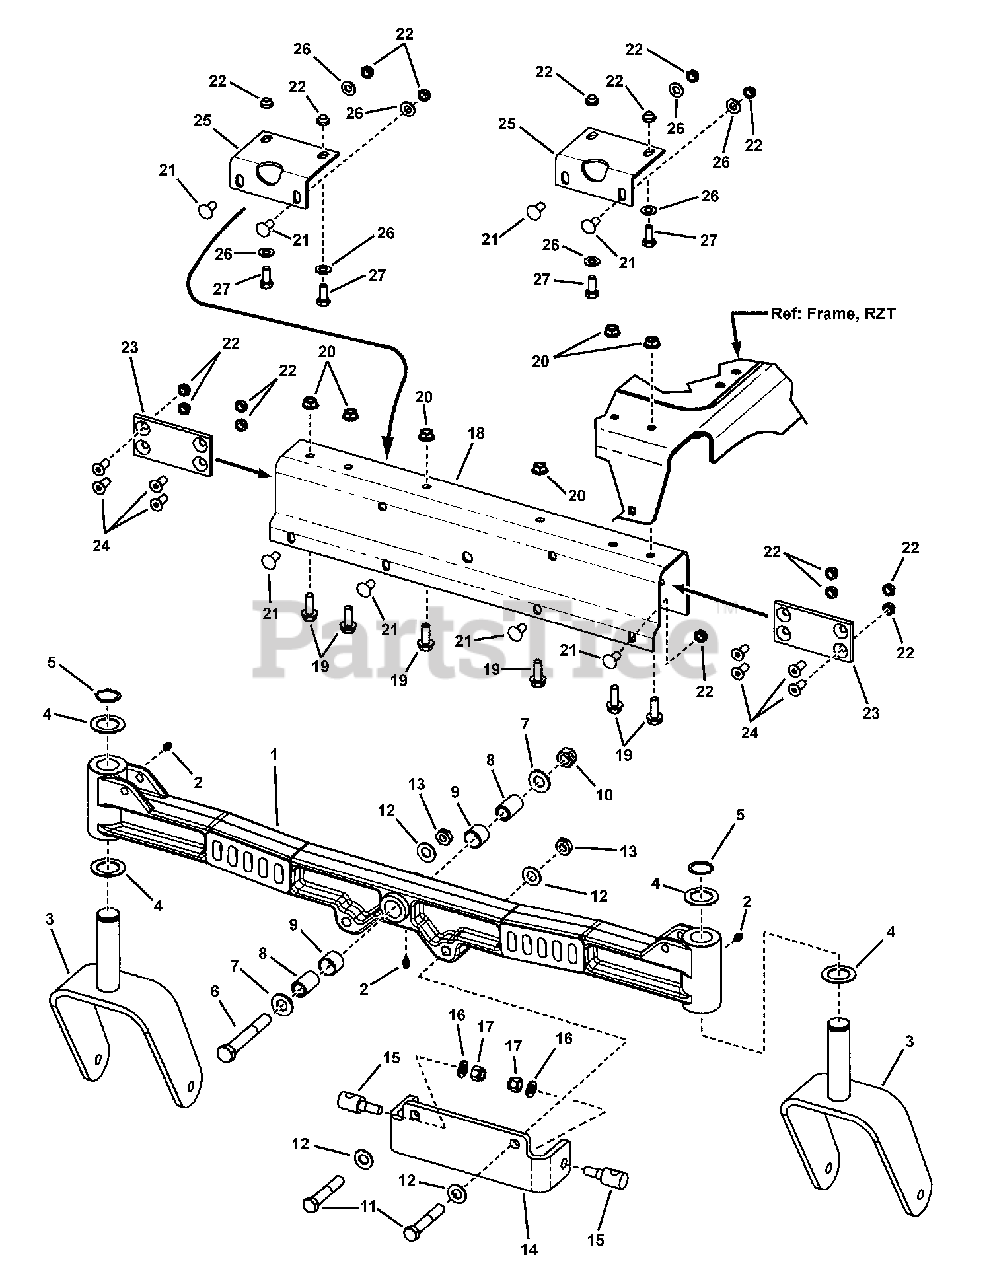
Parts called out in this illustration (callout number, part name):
1	FRONT AXLE, Cast (Cardinal Red)
2	LUBE FITTING, 3/16" Press-In
3	WELDMENT, Caster (Cardinal Red)
4	THRUST WASHER, 1" I.D.
5	RETAINING RING, 1" External
6	SCREW, 1/2-13 x 3-1/2" Hex Head Cap, YZ
7	WASHER, 1/2" SAE Flat
8	SPACER, Axle Pivot
9	BEARING SLEEVE
10	NUT, 1/2-13 Hex Center Lock, GR 5, YZ
11	SCREW, 7/16-20 x 2-1/2" Hex Head Cap, GR 5 (Special Head)
12	WASHER, .47 x .92 x .065 Flat
13	NUT, 7/16-20 Hex Center Lock Jam, GR 5 or B
14	BRACKET, Quick Hitch
15	SWIVEL, 3/8-16 Inline
16	WASHER, 13/32 x 1-1/4" Flat
17	NUT, 3/8-16 Hex Nyloc
18	BRACKET, Axle (Cardinal Red)
19	BOLT, 5/16-18 x 7/8" Hex Flange Lock, YZ
20	NUT, 5/16-18 Hex Flange Lock, GR 5
21	BOLT, 5/16-18 x 3/4" Short Neck Carriage, GR 5
22	NUT, 5/16-18 Hex Top Lock, GR B
23	PLATE, Friction
24	SCREW, 5/16-18 x 1" Flat Head Countersunk
25	BRACKET, Axle Support
26	WASHER, .34 x .69 x .08 Flat
27	SCREW, 5/16-18 x 3/4" Hex Head Cap, GR 5, YZ
